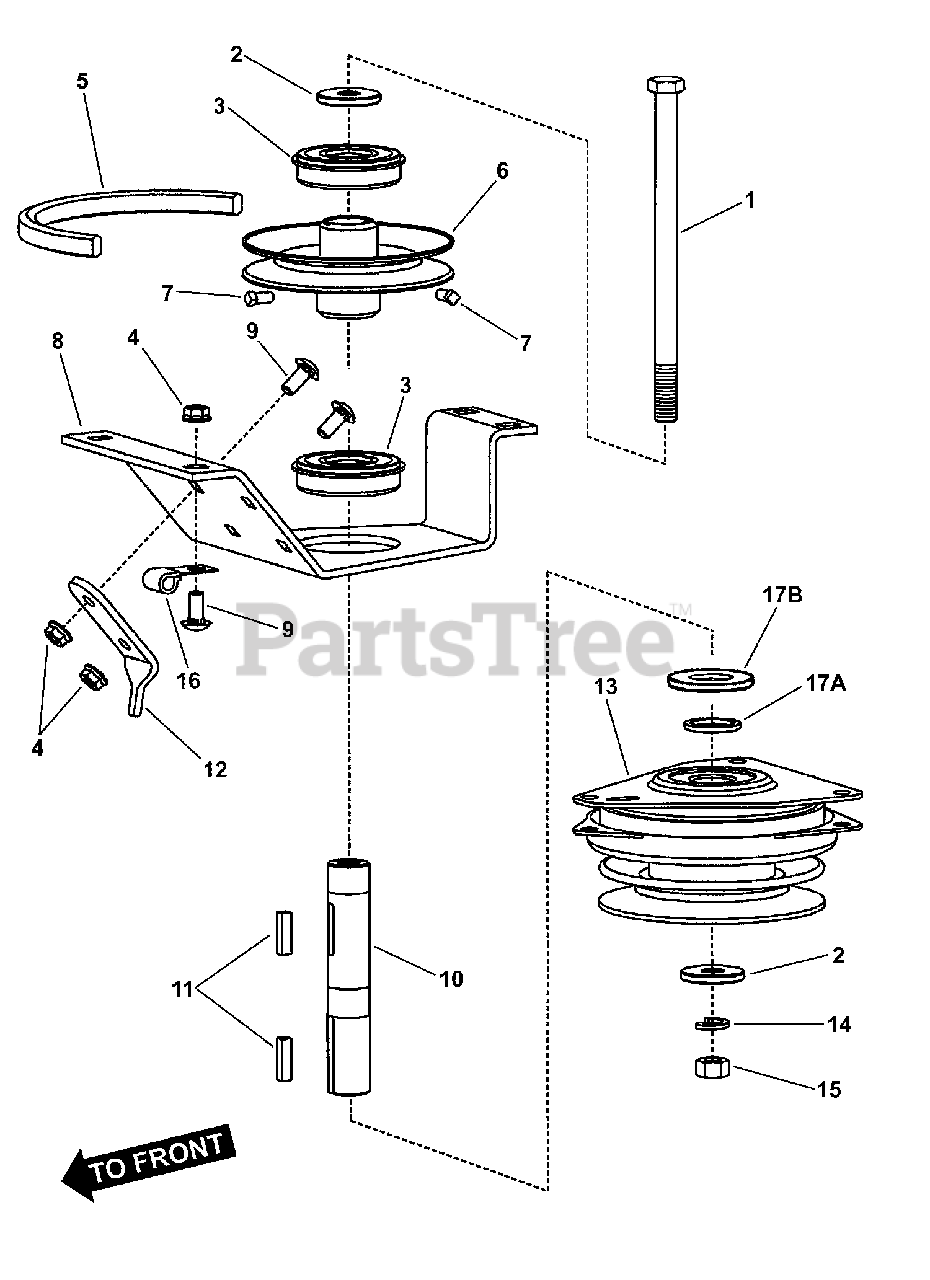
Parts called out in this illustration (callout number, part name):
1	BOLT, 7/16-20 x 8" Hex Head, GR5
2	WASHER, .468 I.D. x 1.50 O.D. x .188 Flat
3	BEARING, 6305 w/Snap Ring
4	NUT, 5/16-18 Hex Flange Lock, GR5
5	V-BELT, 5L Sect. Cog, 50.170" effective length
6	PULLEY, Jackshaft
7	SCREW, 1/4-20 x 1/2" Set w/Patch
8	SUPPORT, Jackshaft- TG 2000
9	BOLT, 5/16-18 x 3/4" Short Neck Carriage, GR5
10	JACKSHAFT
11	KEY 1/4" Square x 1"
12	BRACKET, Anti-Rotation, Ogura
13	CLUTCH, Electric Ogura MA-GT-SN11S (33" units)
14	WASHER, 7/16" Split Lock
15	NUT, 7/16-20 Hex, GR5 or B
16	WIRE CLIP 7/16", Vinyl Covered
17A	SPACER, Jackshaft
17B	SPACER, Clutch (Ogura)
